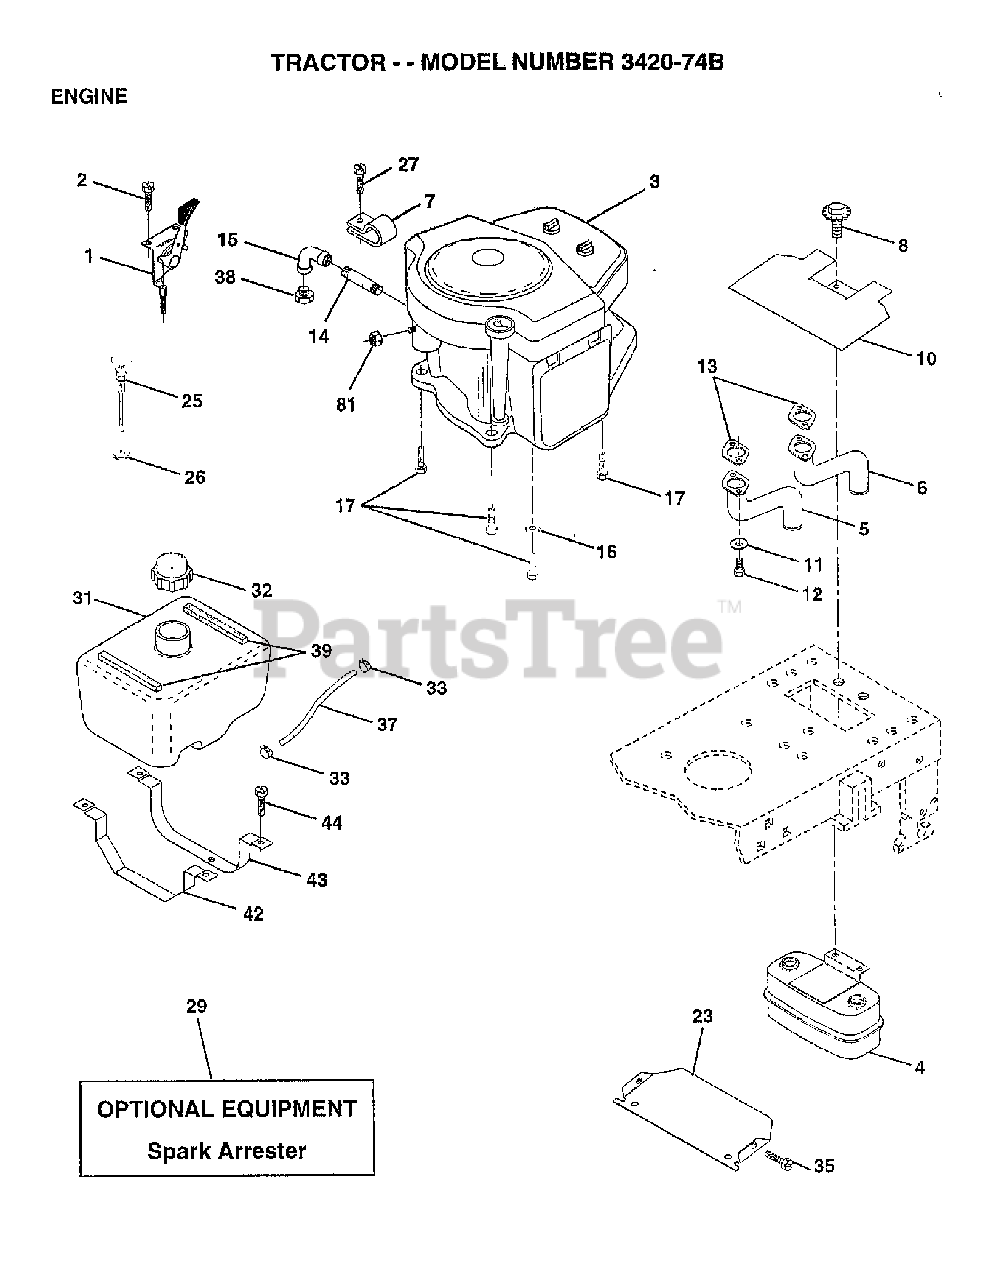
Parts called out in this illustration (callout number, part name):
1	DECK W/DECALS 72" HUS
3	Poulan TBD
4	MUFFLER.TWIN.CYL.LOW.TONE
5	EXHAUST ASM. LEFT
6	EXHAUST ASM. RIGHT
10	SHIELD HEAT LT
11	LOCKWASHER
13	GASKET (B&S 692282)
14	NIPPLE, PIPE 3/8NPT X 4-1/2
15	ELBOW
16	LOCKWASHER
25	CONTROL.CHOKE.51.00.BLK.W/BEND
26	NUT KEPS 3/8 - 24 UNF
27	SCREW.TT.#10-32X.5.3/8.FLANGE
29	KIT.SPARK ARRESTOR(392390 B&S)
33	HOSE CLAMP
35	Screw, Lt
37	LINE FUEL 7.5"
